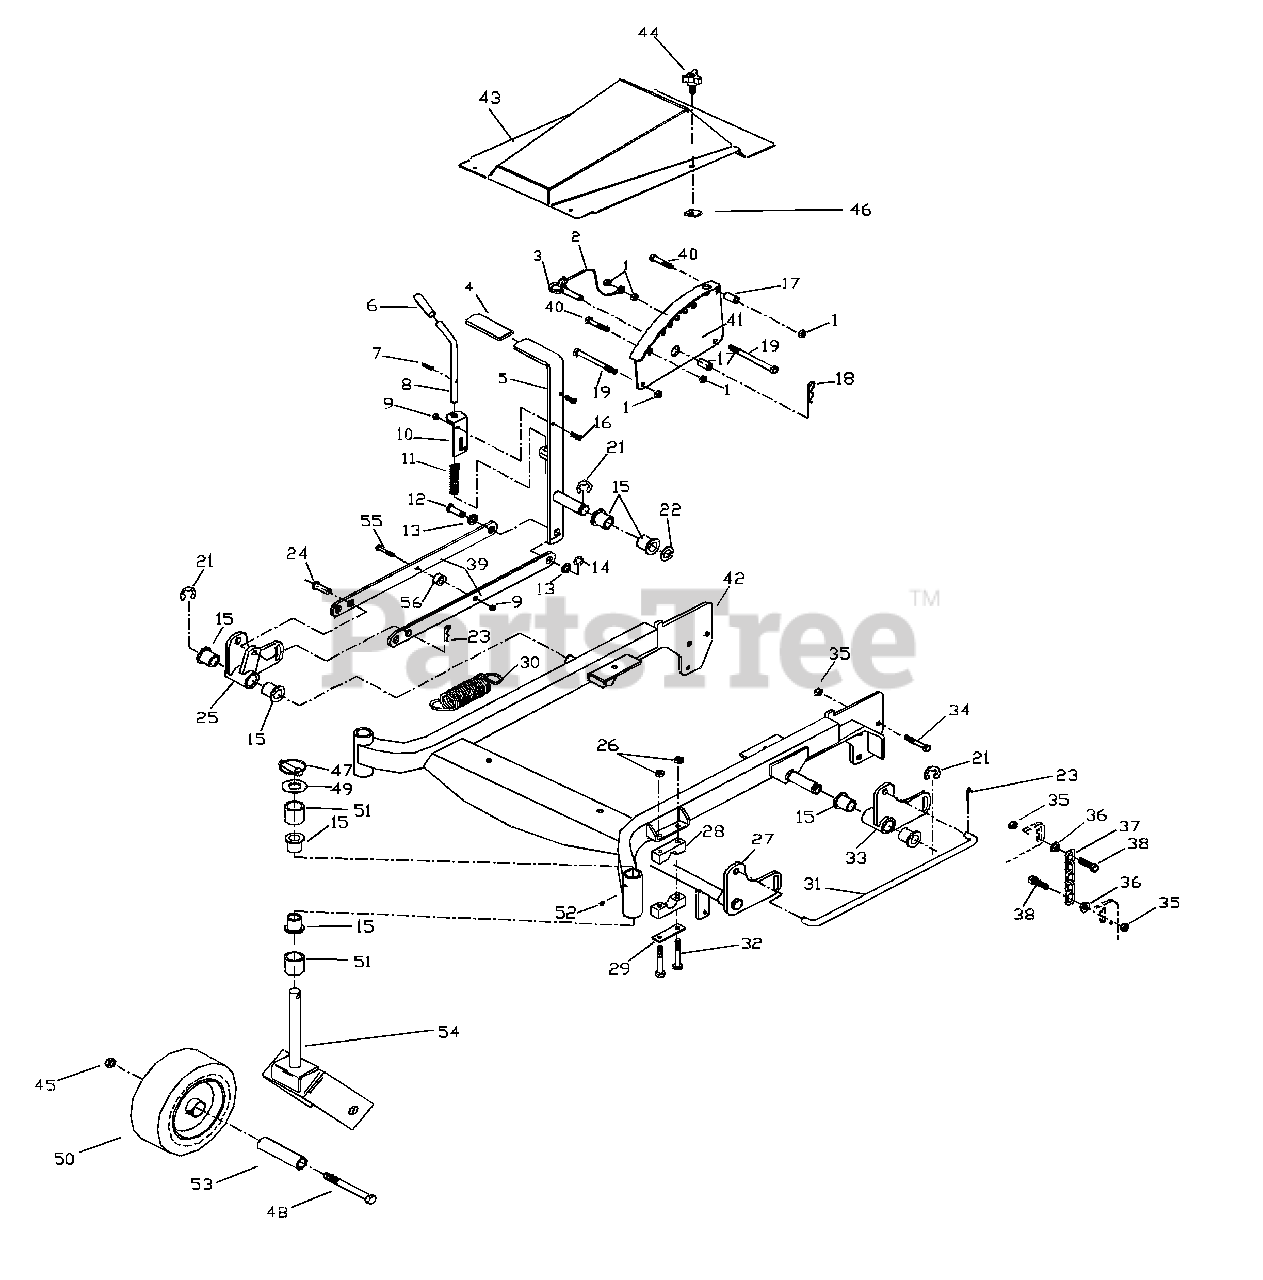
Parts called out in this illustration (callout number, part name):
1	NUT 3/8 CTR. LOCK
5	LIFT LEVER
9	NUT 1/4 CTR. LOCK
12	CLEVIS PIN
13	MACH. BUSHING
14	E-RING .625
15	FLANGE BUSHING
16	HCS 14/ X .750
19	HCS 3/8 X 4.500
21	E-RING .875
22	MACH. BUSHING
23	COTTER PIN
24	CLEVIS PIN
25	BELLCRANK RT.
26	NUT 5/16 CTR. LOCK
27	LIFT WLDMT.
28	PILLOW BLOCK
29	REINF. PLATE
31	CONNECTING ROD
32	HCS 5/16 X 2.500
33	BELLCRANK LT.
34	HCS 7/16 X 1.000
35	NUT 7/16 CTR. LOCK
36	NUT 7/16 WHIZ
37	LIFT CHAIN
38	HCS 7/16 X 1.500
39	FLAT LINKAGE
40	HCS 3/8 X 2.000
41	HEIGHT ADJ. PLATE
44	KNOB
45	NUT 1/2 NYLOC
47	LYNCH PIN 7/16
48	HCS 1/2 X 5.500
49	MACH. BUSHING
50	WHEEL AND TIRE ASM.
50	TIRE ASM - AFTER 04/2002
50	TIRE - AFTER 04/2002
50	RIM - AFTER 04/2002
50	ZERK
50	NOTCHED END CAP
50	ROLLER BEARING
52	ZERK
54	CASTER YOKE
55	HCS 1/4 X 1.250
